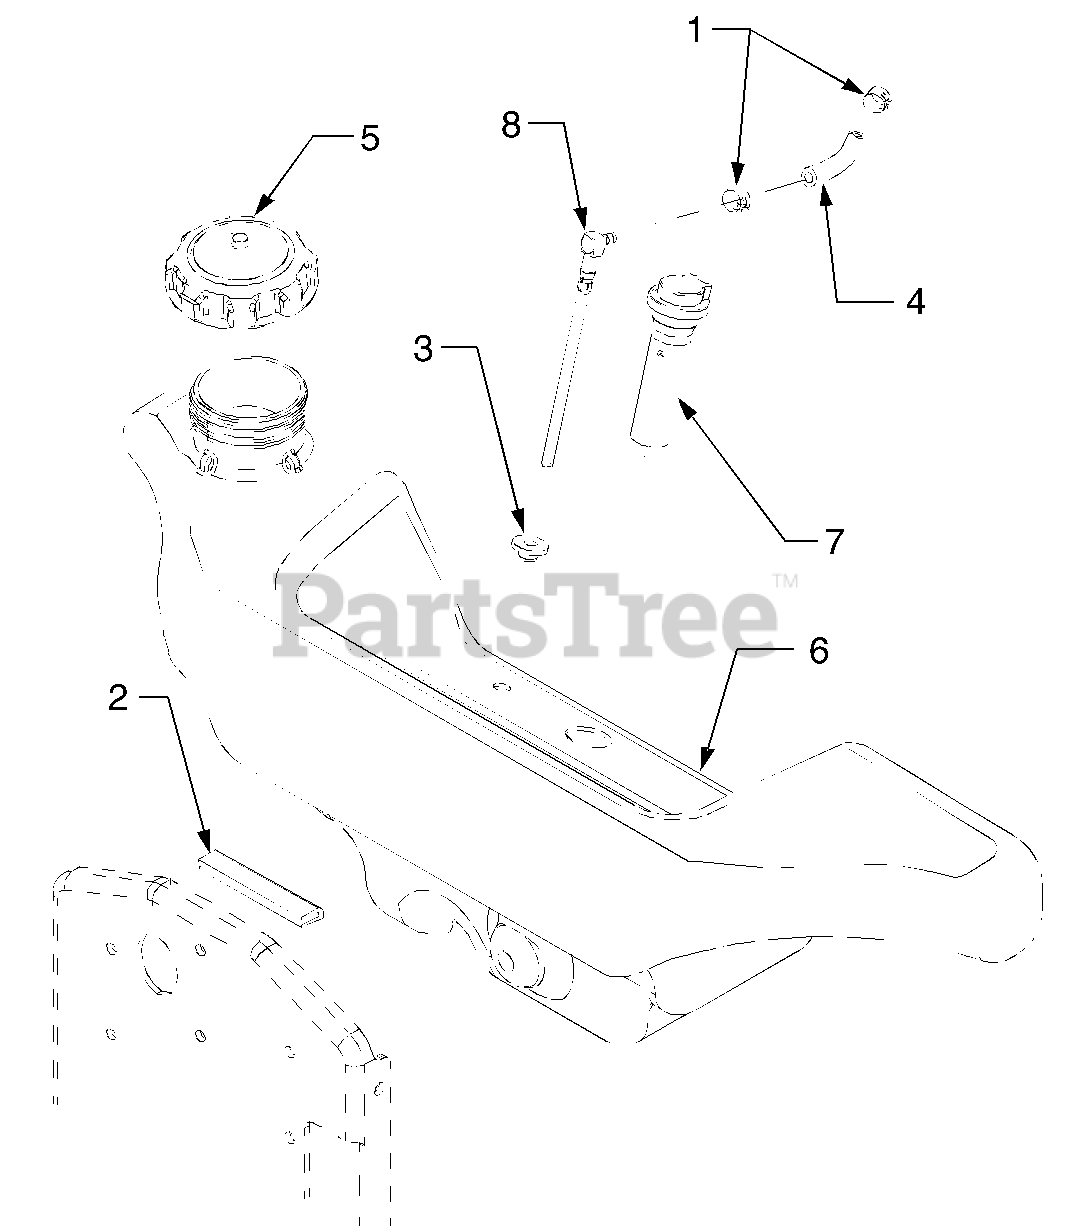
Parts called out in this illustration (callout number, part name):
1	Clamp, Hose
2	Trim, Tank Protector
3	Bushing, Rubber
4	Fuel Line
5	Cap, Fuel
6	Tank, Fuel, 4.5 Gallon
7	Sensor, Low Fuel
8	Fitting, Fuel Pickup
